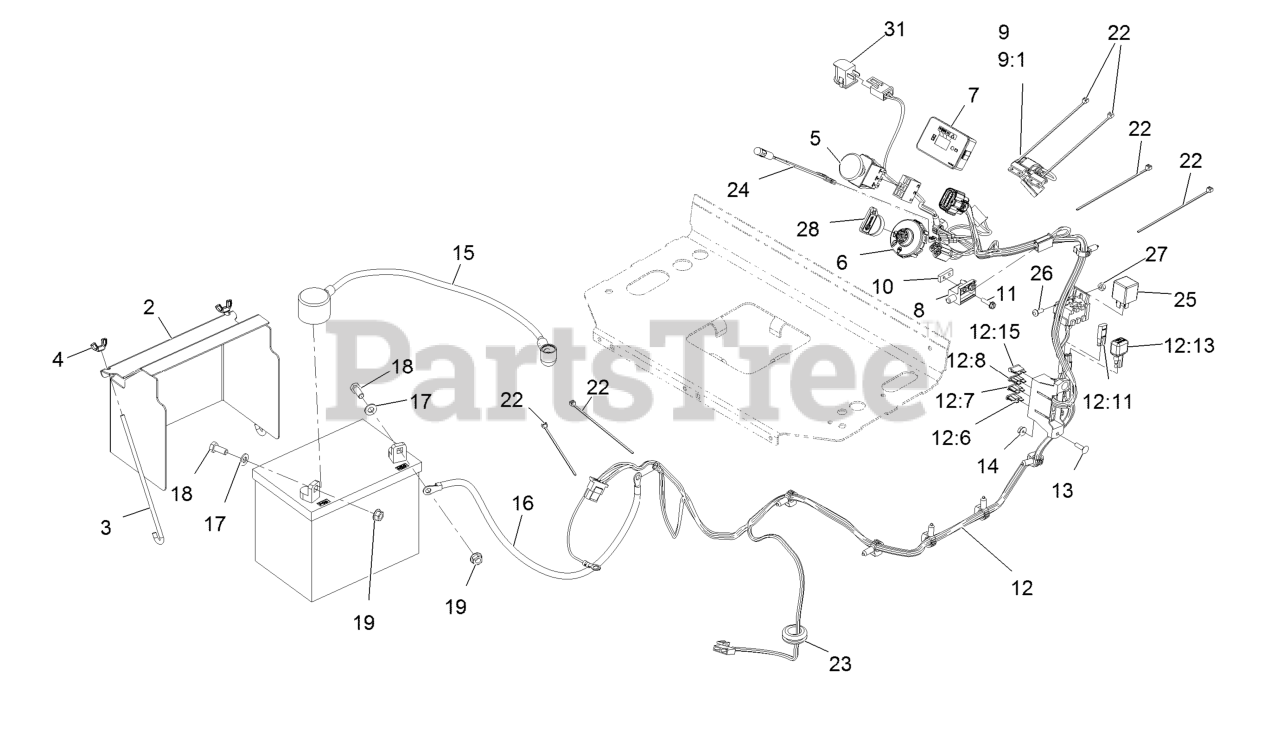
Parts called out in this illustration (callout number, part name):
2	Cover-Battery
3	Bolt-Holddown
4	Wingnut-Nyloc 1/4-20
5	Switch-PTO, On-On-(On)
6	Switch-Ignition
7	Module-Hour Meter
8	Switch-N.C.
9	Harness-Switch, Reed
9:1	Harness-Wire, Reed Switch
10	Plate-Tapped
11	Screw-HWH #10-24 X 3/4
12	Harness, Wire
12:6	Fuse-Blade, 30 Amp
12:7	Fuse-Blade, 25 Amp
12:8	Fuse-Blade, 10 Amp
12:11	Cap-Plug
12:15	Fuse-Blade, 15 Amp
13	Screw-CARR
14	Nut-Whizlock #10-24
15	Cable-Battery, Positive
16	Cable-Battery, Black
17	Washer-5/16 SAE
18	Screw-HH 5/16-18 X 3/4
19	Nut-Hex Flange 5/16-18
22	Tie-Cable 5 1/2 (Small)
23	Grommet
24	Indicator-Red LED
25	Relay-12Vdc 40 Amp
26	Screw-PPH #10-24 X 1/2
27	Nut-Nyloc #10-24
28	Key-Exmark Logo
